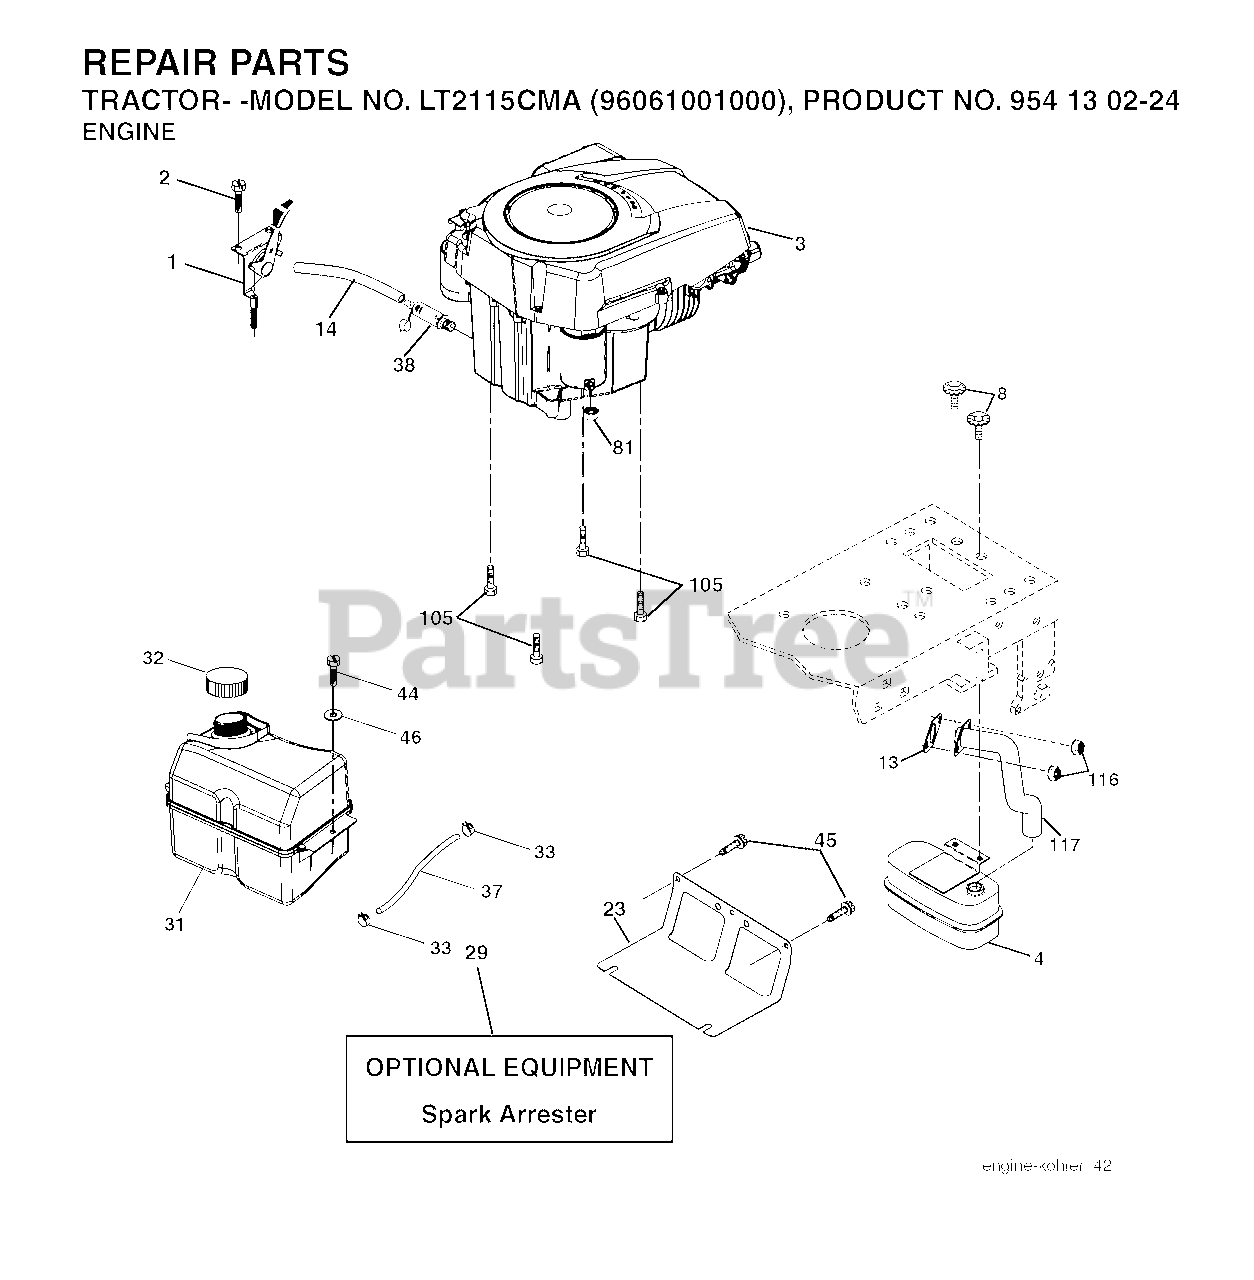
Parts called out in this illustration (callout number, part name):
1	CONTROL.THROTTLE.LT/YT
2	SCREW
4	MUFFLER.SINGLE.CYL.KOHL/B&S
8	BOLT, 5/16-18 X 1 3/4
13	GASKET ENGINE
14	TUBE, DRAIN OIL ASM.
23	SHEILD.BROWNING.DBR.GUARD
29	ARRESTER SPARK (OPTIONAL)
31	TANK FUEL
32	FUEL CAP
33	HOSE CLAMP
37	LINE.FUEL.20
38	PLUG DRAIN OIL EASY
44	SCREW HEXWSHR 1/4-20X3/4
45	SCREW, 3/8-16X3/4
81	NUT
105	SCREW 3/8-16X1
116	NUT.HEX.FLANGE.TOPLOCK
117	TUBE EXHAUST
